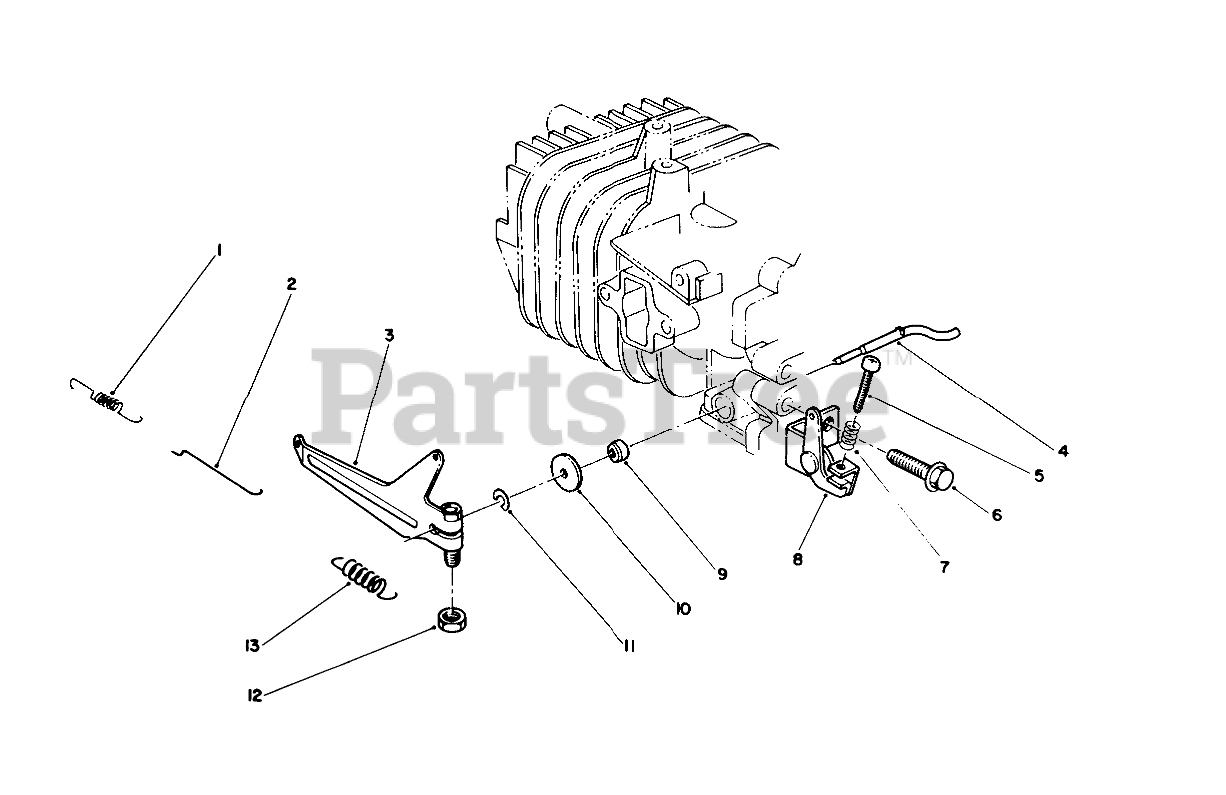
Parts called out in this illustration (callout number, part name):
1	CARB SPRING
2	CARB ROD
3	GOVERNOR ARM
4	SHAFT
5	SCREW
7	SPRING
8	GOV SPR BRKT
9	SEAL-OIL
10	WASHER
11	E-RING
13	GOV SPRING
